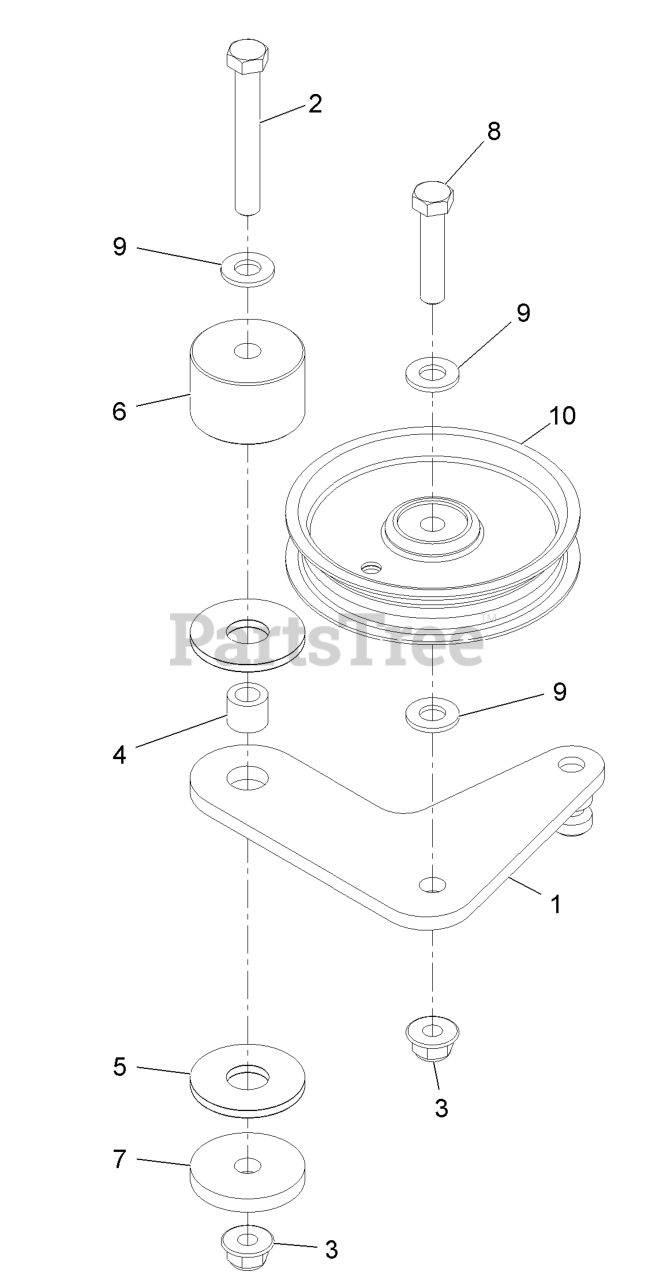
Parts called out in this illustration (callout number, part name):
1	PLATE-IDLER
2	SCREW-HH
3	NUT-HF, NI
4	BUSHING-LEVER, LIFT
5	WASHER-FRICTION, COMPOSIT
6	HUB-IDLER
7	WASHER-PLAIN
8	SCREW-HH
9	WASHER-FLAT
10	PULLEY-IDLER
